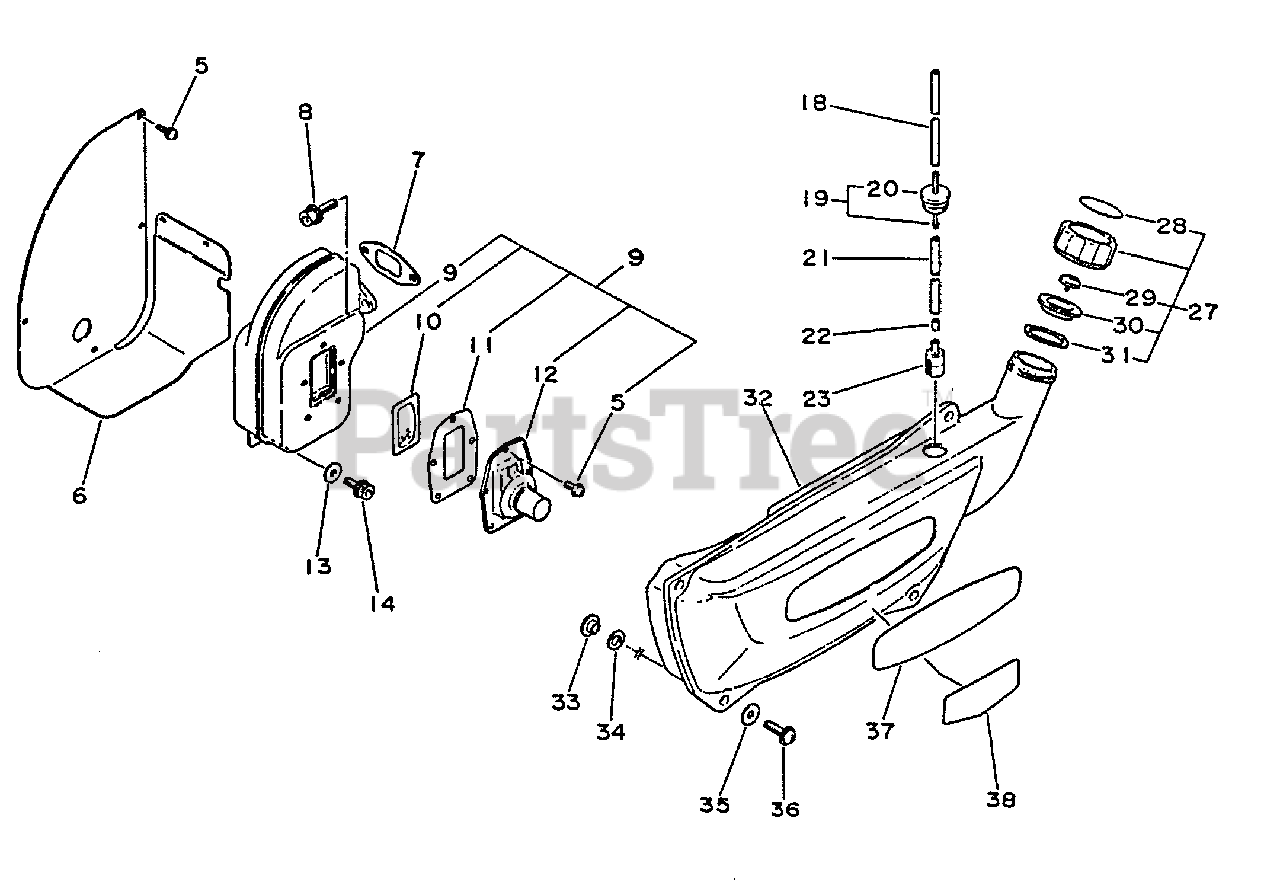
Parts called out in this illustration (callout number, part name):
5	SCREW - 4X10
6	INSULATOR
7	GASKET, EXHAUST
8	SCREW - 6X20
9	MUFFLER ASSY
10	SCREEN, SPARK ARRESTOR
11	GASKET, EXHAUST
12	GUIDE, EXHAUST
13	WASHER - 5
14	SCREW - 5X14
18	PIPE - FUEL
19	GROMMET KIT
21	PIPE - FUEL
23	FILTER, FUEL
27	CAP ASSY
28	LABEL - FUEL MIX
30	HOLDER, VENT
31	GASKET, CAP
32	TANK, FUEL
34	WASHER - RUBBER
36	SCREW - 5X20
37	LABEL - ECHO
38	LABEL - MODEL
